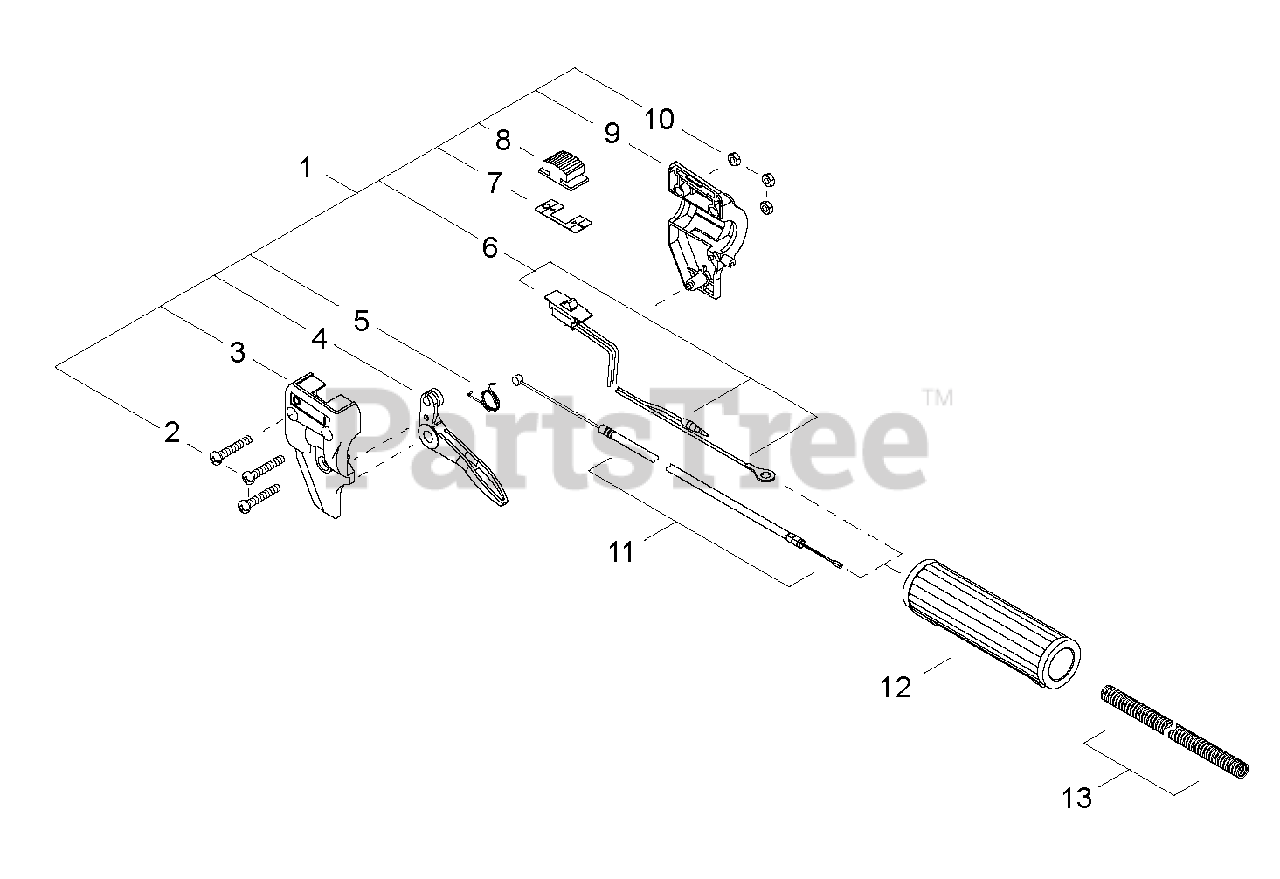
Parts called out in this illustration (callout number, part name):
1	THROTTLE CONTROL ASSY
2	SCREW - 5X30
3	HANDLE, CONTROL - LEFT
4	TRIGGER, THROTTLE
5	SPRING, TRIGGER
6	SWITCH, IGNITION
7	PLATE, SWITCH
8	BUTTON, SWITCH
9	HANDLE, CONTROL - RIGHT
10	NUT - 5
11	CABLE, THROTTLE
12	GRIP
13	TUBE, PROTECTIVE - PLASTIC
